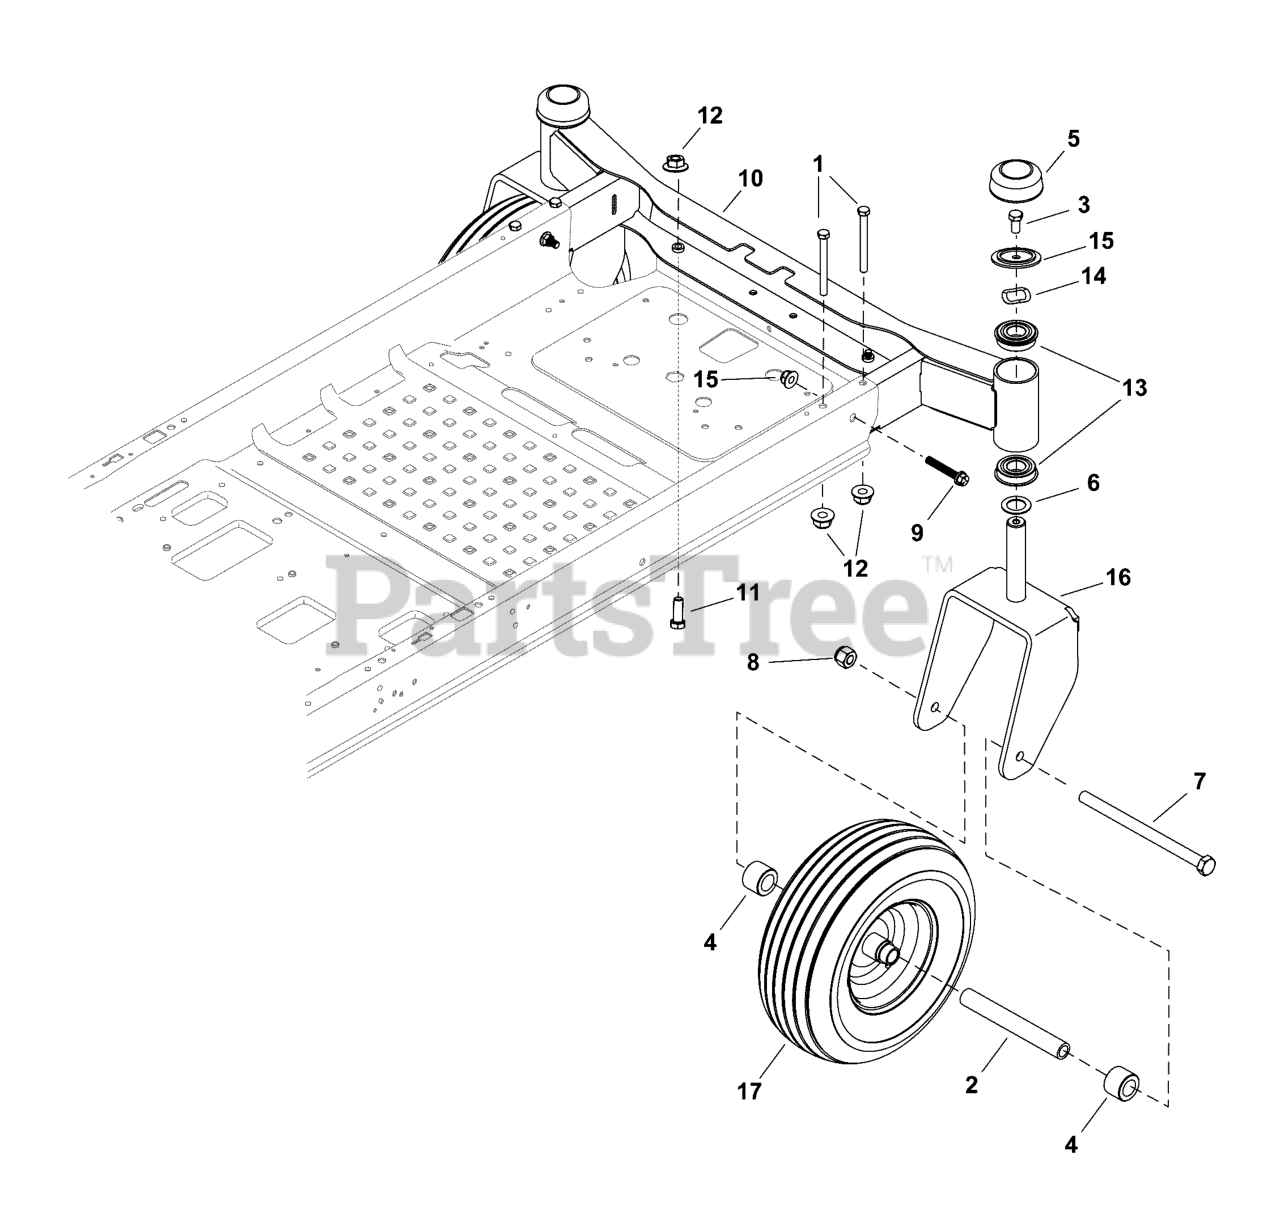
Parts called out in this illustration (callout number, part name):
1	SCREW, 3/8-16 X 3.75 GR5
3	SCREW, 3/8-16 X .75 GR 5
5	CAP, Caster Axle
6	WASHER, 1.010X1.560X.060
7	BOLT, Shoulder
9	SCREW, 3/8-16 X 2.00 GR5
10	ASSEMBLY, Front Axle
11	SCREW, 3/8-16 X 1 GR5
12	NUT, 3/8-16, Hex Flange
13	BEARING, Ball
14	WASHER, Wave
15	SPACER, Shoulder
16	YOKE, Caster Wheel
17	CASTER, Wheel
